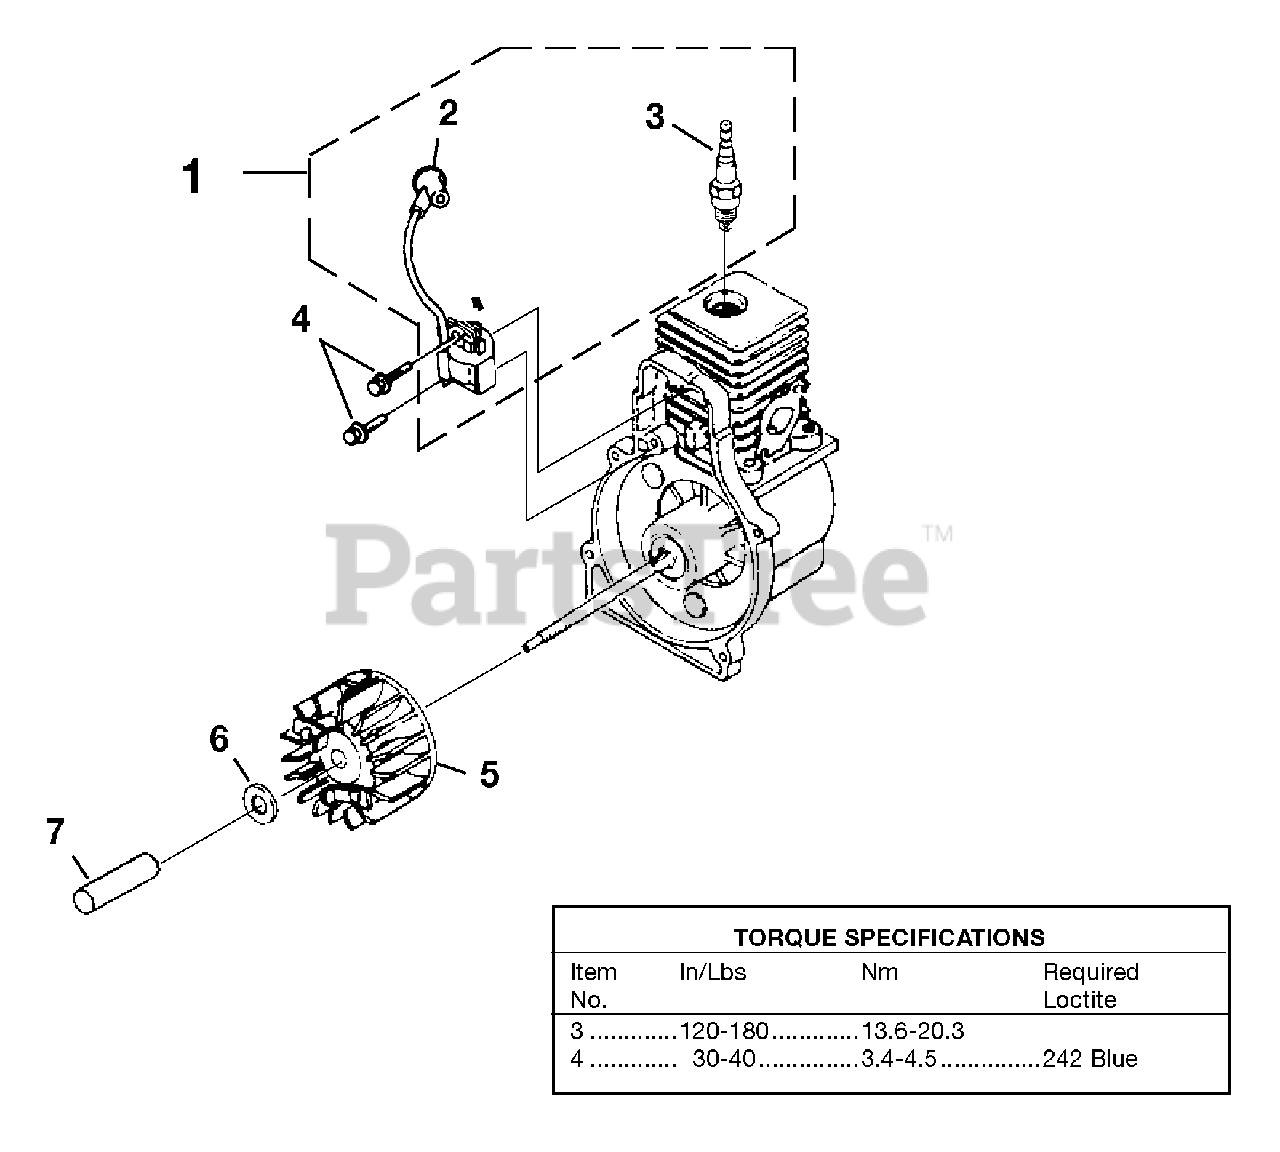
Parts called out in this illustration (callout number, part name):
1	IGNITION KIT w/ Module
2	IGNITION MODULE
3	SPARK PLUG
4	SCREW-Thread Form. (8-32 x 1)
5	ROTOR & STARTER PAWLS
6	WASHER-Flat
7	SPACER-Fan
